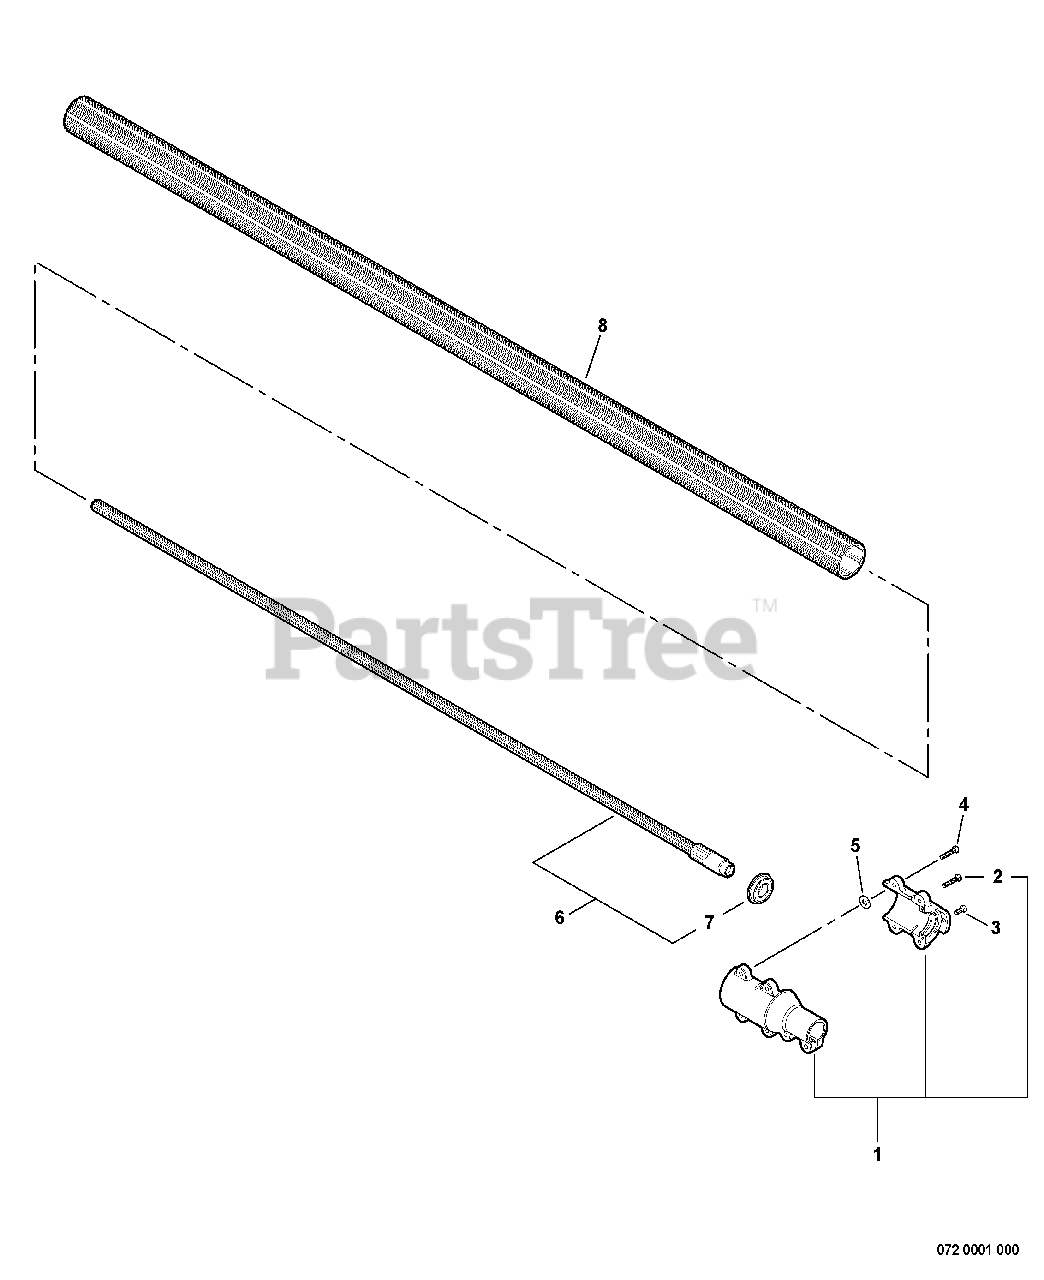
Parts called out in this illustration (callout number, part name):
1	COUPLING ASSY, LOWER
2	BOLT 5×20
3	SCREW M5×10
4	BOLT 5×20
5	WASHER 5
6	DRIVESHAFT ASSY, LOWER
7	BEARING, BALL 15×32×9
8	PIPE, MAIN - ORANGE
